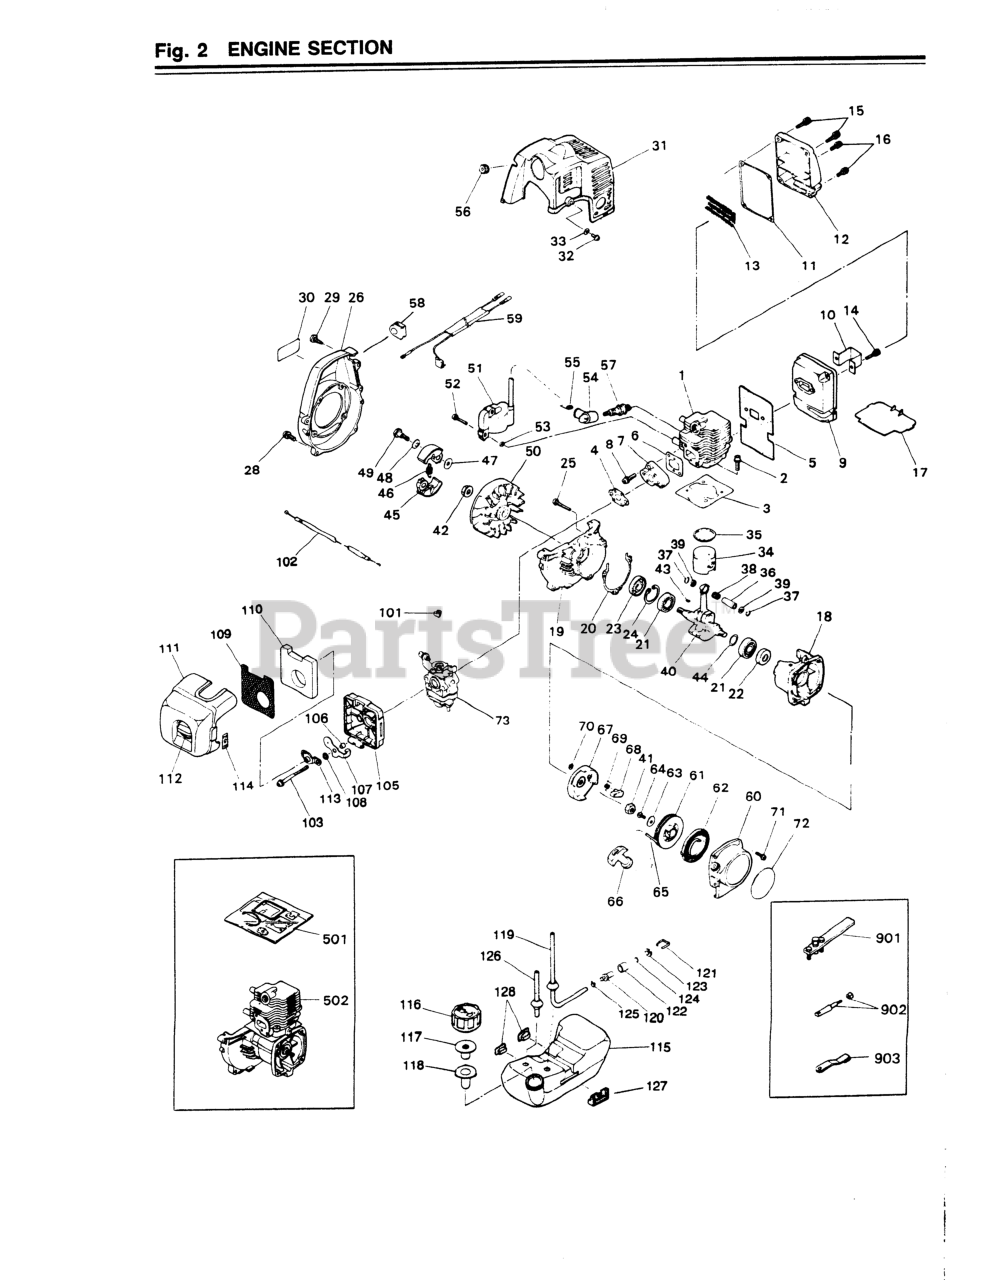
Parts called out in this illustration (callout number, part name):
2	BOLT, M5 X 22
8	SCREW, M5 X 20
13	ARRESTER
14	BOLT, M6 X 18
15	BOLT, M5 X 22
16	BOLT (USE 3310-31720)
18	CRANKCASE (RPLS -21100)
19	CRANKCASE (RPLS -21100)
21	BEARING
23	SEAL, OIL (RPLS 1140-21220)
24	RING, SNAP, M28 x 1.2
25	SCREW, M5 x 30
28	SCREW, M5 X 20
29	SCREW, HOUSING
32	SCREW, M4 x 12
33	WASHER
34	PISTON
35	RING, PISTON (RPLS 1850-41210)
36	PIN, PISTON 5x8x26
39	WASHER
43	KEY
47	WASHER, FLAT (USE 182303)
49	BOLT
52	SCREW, M4 X 22
55	SPRING
56	GROMMET
61	REEL
62	SPRING, SPIRAL
63	WASHER (NO LONGER AVAIL)
69	SPRING, RETURN
70	E-RING
71	SCREW, M4 X 16
72	LABEL
101	CAP, CABLE END
102	CABLE COMP (RPLS 1633-83100)
105	BODY (RPLS -82110)
106	SLEEVE
109	SCREEN
110	ELEMENT
112	KNOB (RPLS 1600-33140)
114	LABEL
117	VALVE (NO LONGER AVAILABLE)
119	PIPE COMP (NO LONGER AVAIL)
120	5500-85400 (RRLS. 1750-85300)
121	5500-85400 (RRLS. 1750-85300)
123	RETAINER
125	CLIP (REPLACES 2841-31280)
127	CUSHION (S)
128	CUSHION (F)
502	BLOCK, SHORT
902	(H) ROD ASSY
NI	SHIM (NO LONGER AVAILABLE)
NI	RECOIL
